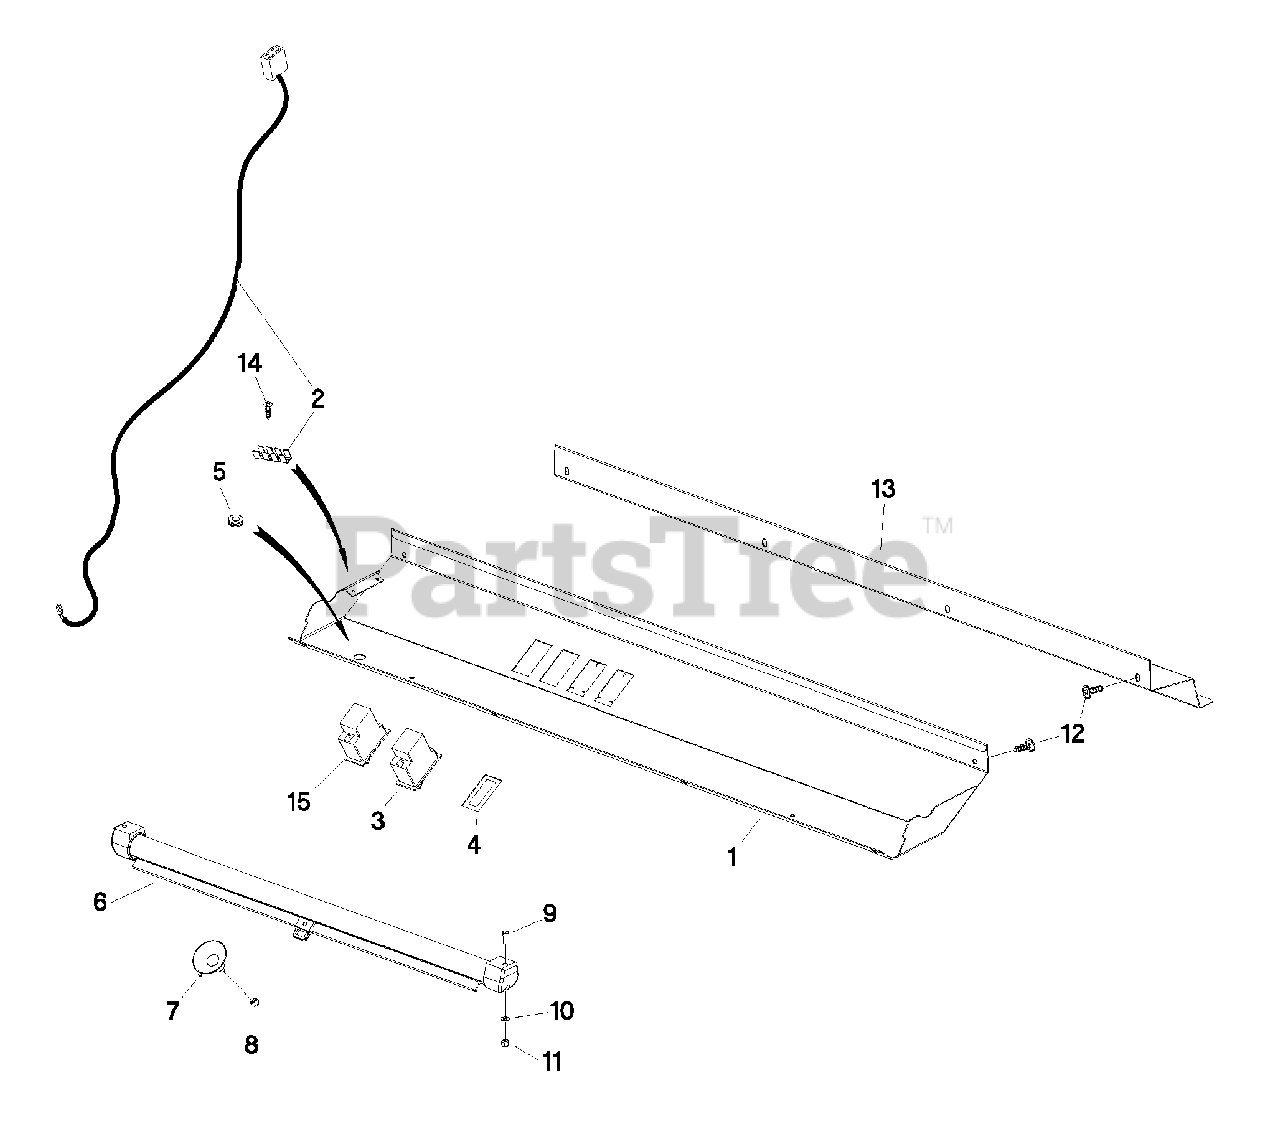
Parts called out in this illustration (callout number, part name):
1	Frame cover panel front top
3	Switch wiper-washer system
4	Blind cover
5	Blind plug 12mm
7	Nipple with screw
9	Oval countersunk head screw M4x15
10	Shim disk M4
12	Sheet metal screw 4.8x16
13	Frame cover panel rear top
14	Sheet metal screw 3.5x16
15	Switch (13.350) 1-stage
